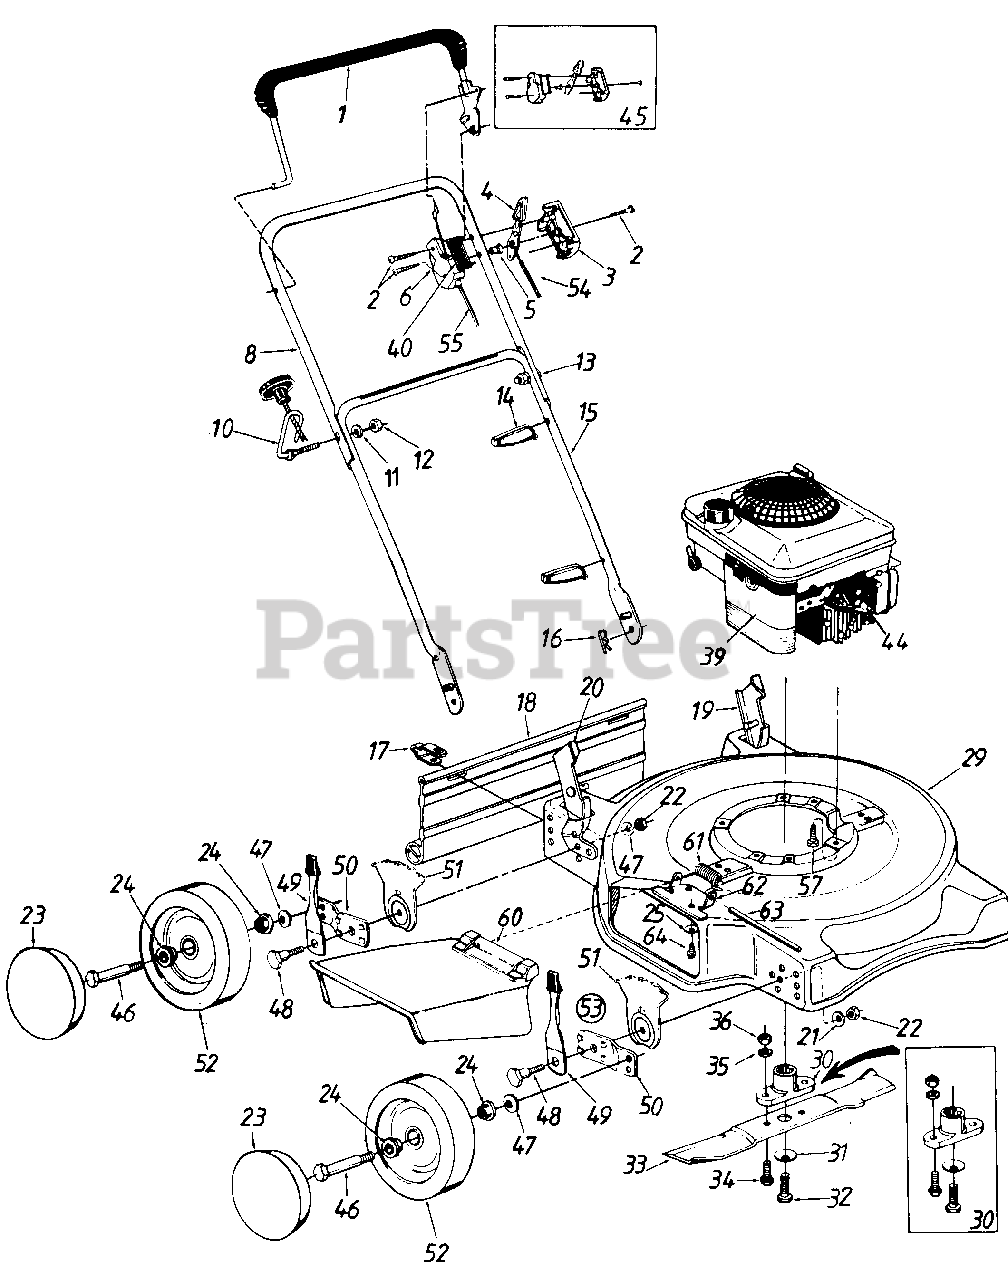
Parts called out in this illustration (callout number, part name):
2	SCREW-TRUSS MACH
3	PANEL HALF-CONTROL
4	LEVER-THROTTLE CONT-REV
5	PIN-CONTROL DISC
6	PANEL HALF-CLUTCH
8	HANDLE-UPPER
10	SCREW-RECOIL HANDLE GUIDE
11	WASHER-LOCK-5/16
12	NUT-HEX 5/16-18
13	BOLT-CARRIAGE-CURV 5/16-18 X 1.38
14	TIE-CABLE
15	LOWER HANDLE
16	PIN-INTERN COT-5/16 DIA
17	CLIP-HINGE
18	FLAP-RR
19	BRACKET ASSY-HDLE-LH
20	BRACKET ASSY-HDLE-RH
21	WASHER-BELL .390 ID X 1.375 X .062
22	NUT-HEX 3/8-16
23	HUB CAP
24	BEARING-BALL
25	WASHER-SPRING BELL
31	WASHER-BELL
32	SCREW-HEX 7/16-20 X 1.50
33	BLADE-19.88IN
34	SCREW-HEX 3/8-24 X 1 LG
35	WASHER-LOCK-3/8
36	HEX NUT 3/8-24 THD.
44	INSULATOR-SPARK PLUG
45	KIT-THROTTLE CONTROL
46	SCREW-SHLD .498 DIA X 1.450
47	WASHER-BELL .400 ID X .88 X .060
48	SCREW-SHLD
49	LEVER & KNOB ASSY
51	PLATE-HGT ADJ
52	WHEEL ASSY W/TIRE
53	ADJUSTER ASSY-HGT-RH
54	WIRE-THROTTLE-52 IN
55	WIRE-THROTTLE
57	SCREW-HEX R
60	DEFLECTOR ASSY-CHUTE
61	SPRING-TORSION
62	PLATE-ADAPTER
63	PIN-HINGE
64	SCREW-HEX WASH SF TAPP
17036-0483	DECK ASSEMBLY-20INCHARCOAL - CHARCOAL GRAY (0483)
17036-0498	DECK ASSEMBLY-20IN(CUB YELLOW) - OLD CUB YELLOW (0498)
17036-0629	DECK ASSEMBLY-20INSILVER FLAK - SILVER FLAKE (0629)
17036-0638	DECK ASSEMBLY-20IN - MTD/TROY-BILT RED (0638)
17036-0662	DECK ASSEMBLY-20IN(OYSTER GRAY) - OYSTER GRAY (0662)
